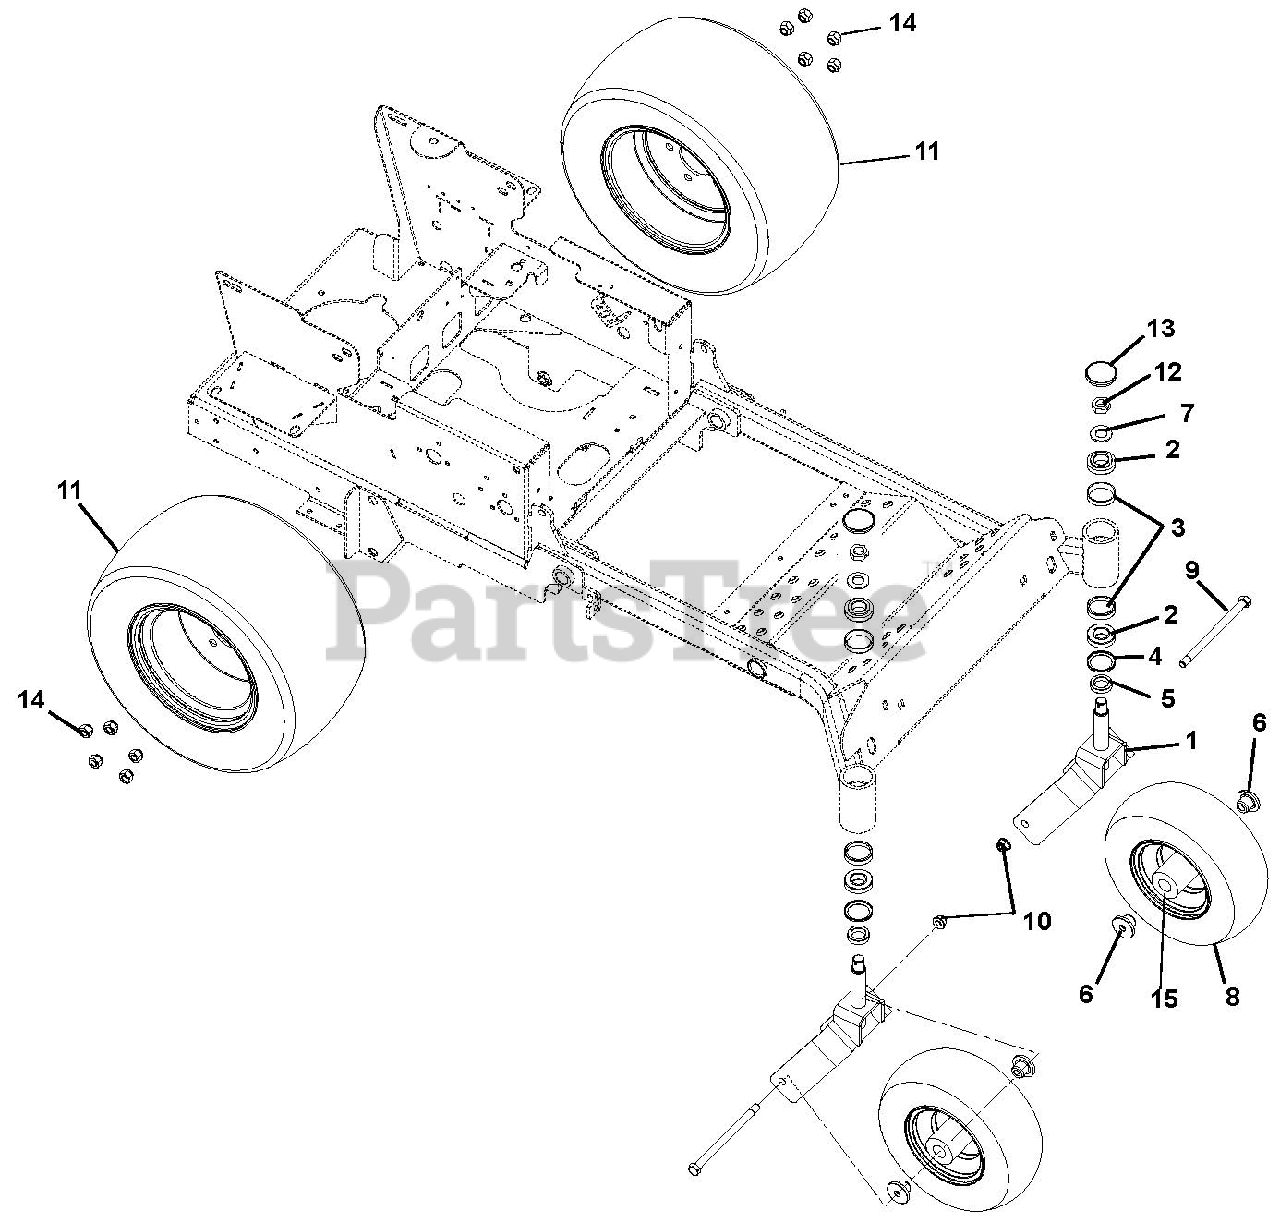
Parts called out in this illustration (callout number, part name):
1	Weldment, Front Fork
2	Bearing, Cone with Grease, 1.0 x .58
3	Bearing, Cup 1.980 x .420
4	Bearing Seal 1.5 x 2 x .18
5	Spacer, PM, 1.03 I.D. x 1.5 O.D. x .375
6	Spacer, Wheel
7	Washer, Flat-Steel .812 x 1.50 x .135
8	Tire/Wheel Assembly, 13 x 5.00-6
8	Tire/Wheel Assembly 4.80-8
9	Bolt, Hex .50-13 x 7.50 Grade 5
10	Nut, Nyloc Flange .50-13
11	Tire/Wheel Assembly, 20 x 10.00-10
11	Rim and Hub Assembly 4.10/3.50 x 6
12	Nut, Center Lock Jam .75-16
13	Cap, Dust
14	Wheel Nut .50-20
15	Bearing, 25MM ID x 52MM OD x 15MM
